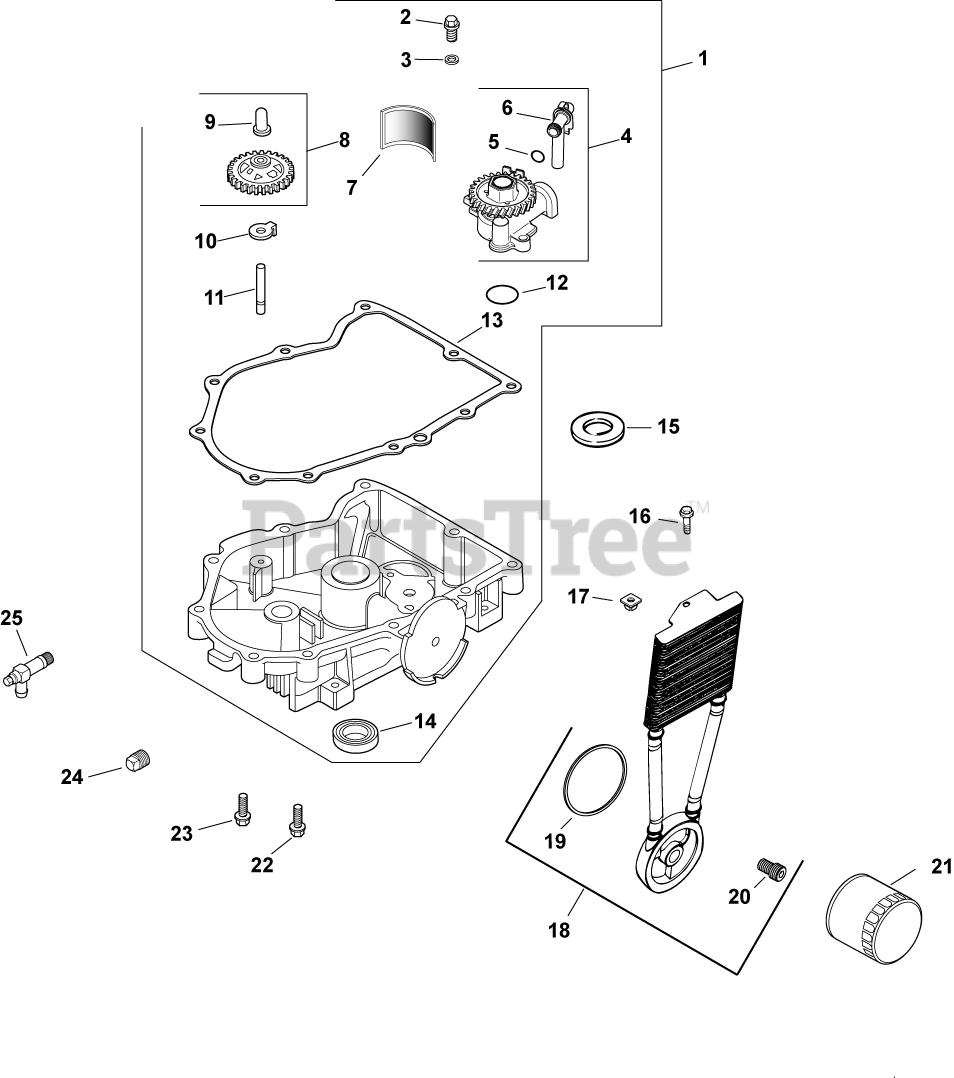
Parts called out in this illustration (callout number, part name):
1	KIT, OIL PAN ASSEMBLY - (#2419932S)
2	SCREW,FLG THD FRM M6X1.0X25-(#25086395S)
3	WASHER, FLAT 6 MM
4	PUMP ASSEMBLY, OIL-USE 24 393 53-S
5	O-RING, OIL PICK-UP
6	KIT, OIL PICK-UP TUBE
7	SCREEN, OIL
8	KIT, GOVERNOR GEAR W/PIN
9	PIN, GOVERNOR REGULATING
10	TAB, LOCKING
11	SHAFT, GOVERNOR GEAR
13	KIT,OIL PAN GASKET USE 24 041 66-S
14	SEAL, OIL (KM)-USE 25 032 06-S
15	SHIM, THRUST (BLACK .686MM)
16	SCREW, TAP M6X1.7X18
17	NUT, PLASTIC (KM)-USE 25 100 37-S
18	KIT, OIL COOLER
19	O-RING, OIL COOLER
20	NIPPLE, OIL FILTER
21	OIL FILTER
22	SCREW, HEX FLANGE -USE 24 086 17-S
23	SCREW, FLG M8X1.25X45
24	PLUG, SQ HD PIPE 3/8"
25	VALVE, OIL DRAIN MEDIUM
